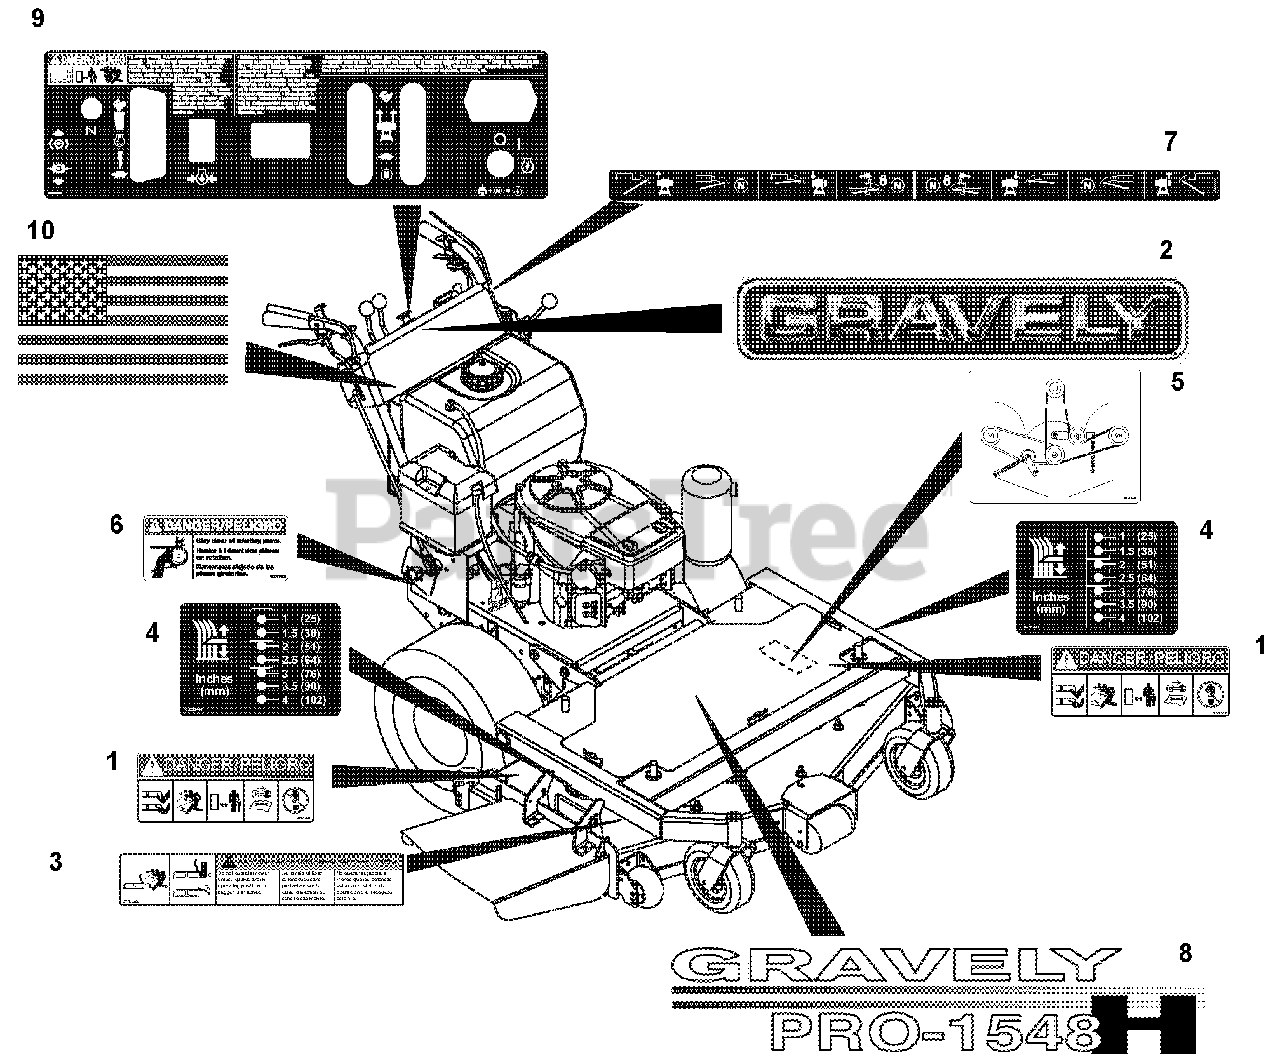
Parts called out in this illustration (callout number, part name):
1	Decal, Mower Pan Head Danger
2	Decal- 15" Gravely Logo
3	Decal, Warning
4	Decal-Height of Cut- Floating
5	Decal-Belt Diagram-3 Spindle
6	Decal-Danger-Belt Rotating
7	Decal, Steer Levers (108, 109)
8	Decal-Pro 1748H (108)
9	Decal, Control (108, 109)
10	Decal, American Flag
